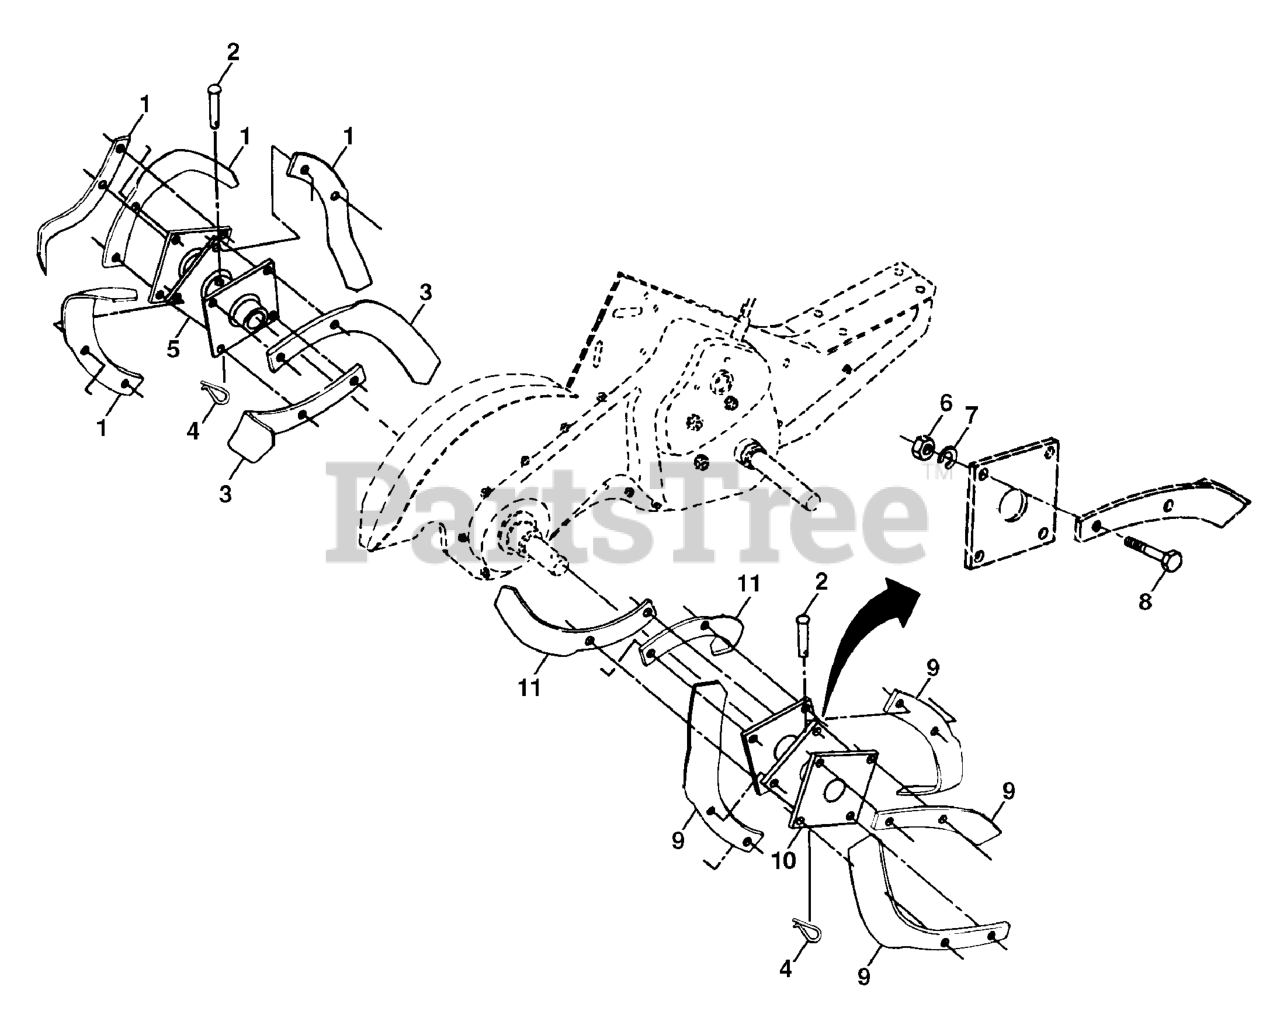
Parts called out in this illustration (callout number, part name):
1	TINE TI
2	PIN RETAINING SCREW
3	TINE.LH.12"(72L)
4	SPRING RETAINER
5	HUB.&.PLATE.ASM.LH
6	NUT
7	WASHER, LOCK 3/8
8	BOLT.HEX.001X20.37-24X1.ZINC
9	TINE TI
10	HUB & PLATE ASM RH
11	TINE.RH.12"(72R)
